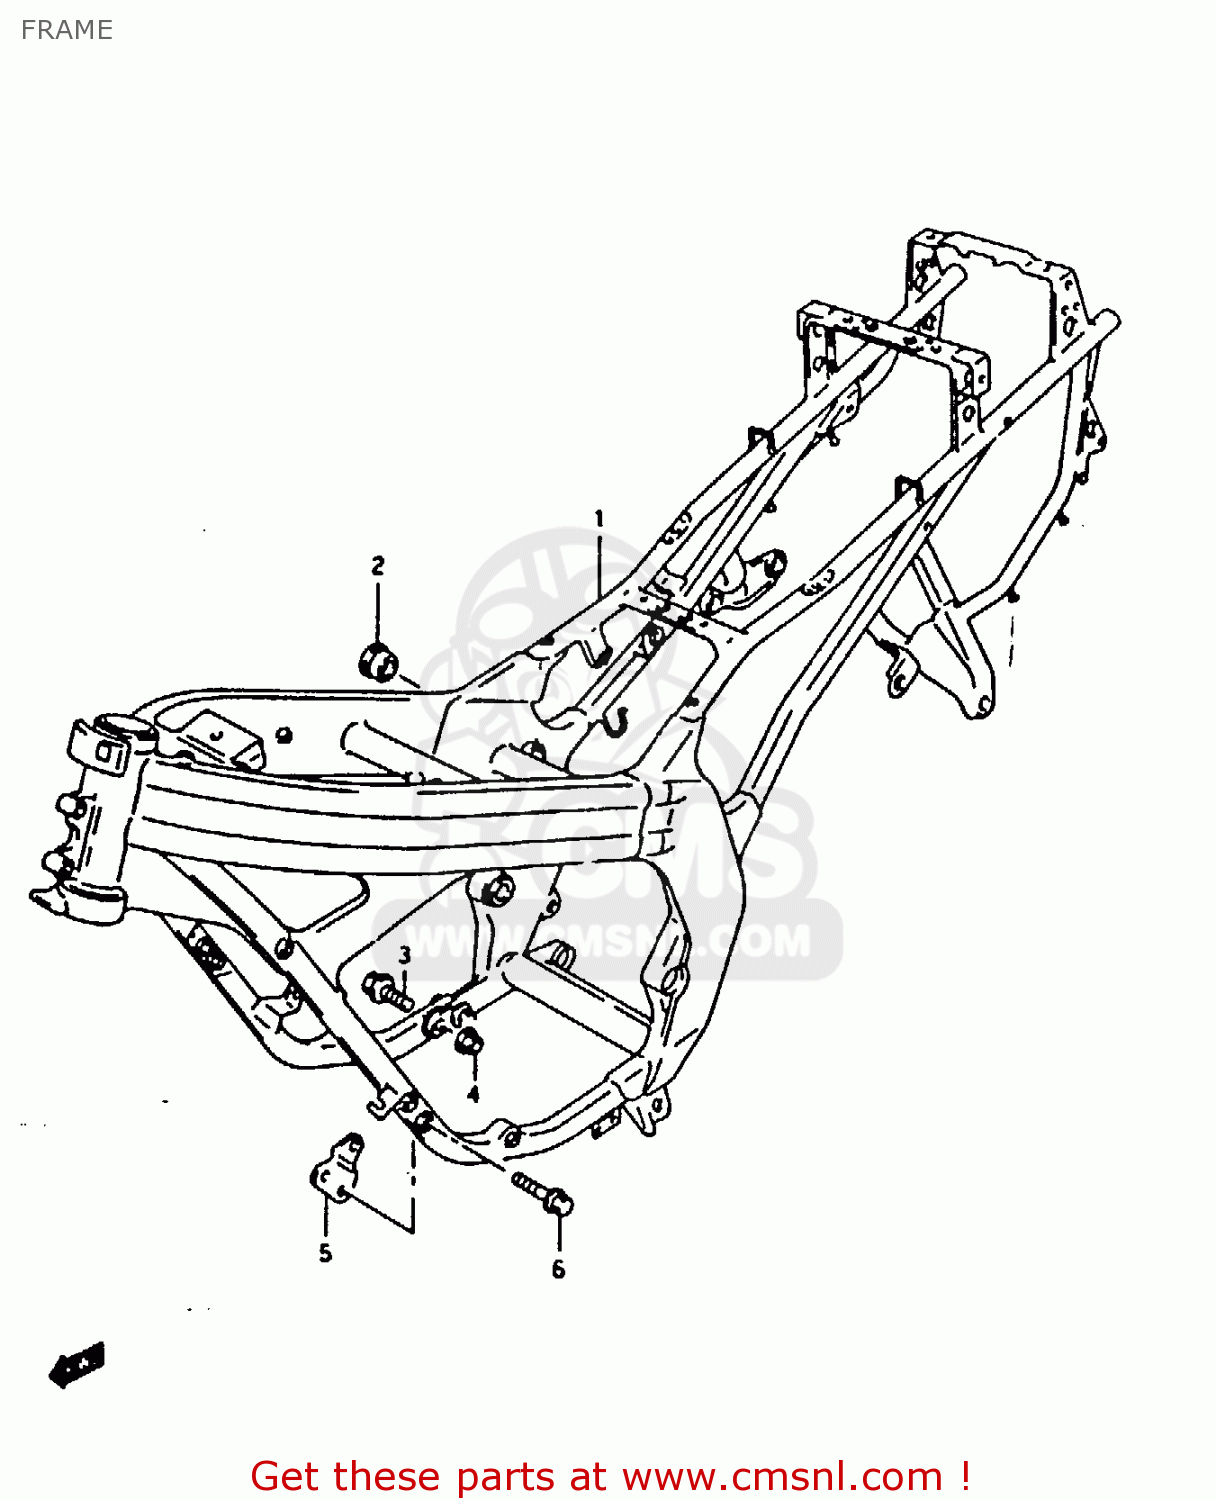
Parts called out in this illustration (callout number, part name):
1	FRAME (SILVER)
2	PLUG
3	BOLT
4	NUT
5	PLATE,ENG MTG(SILVER)
6	BOLT
